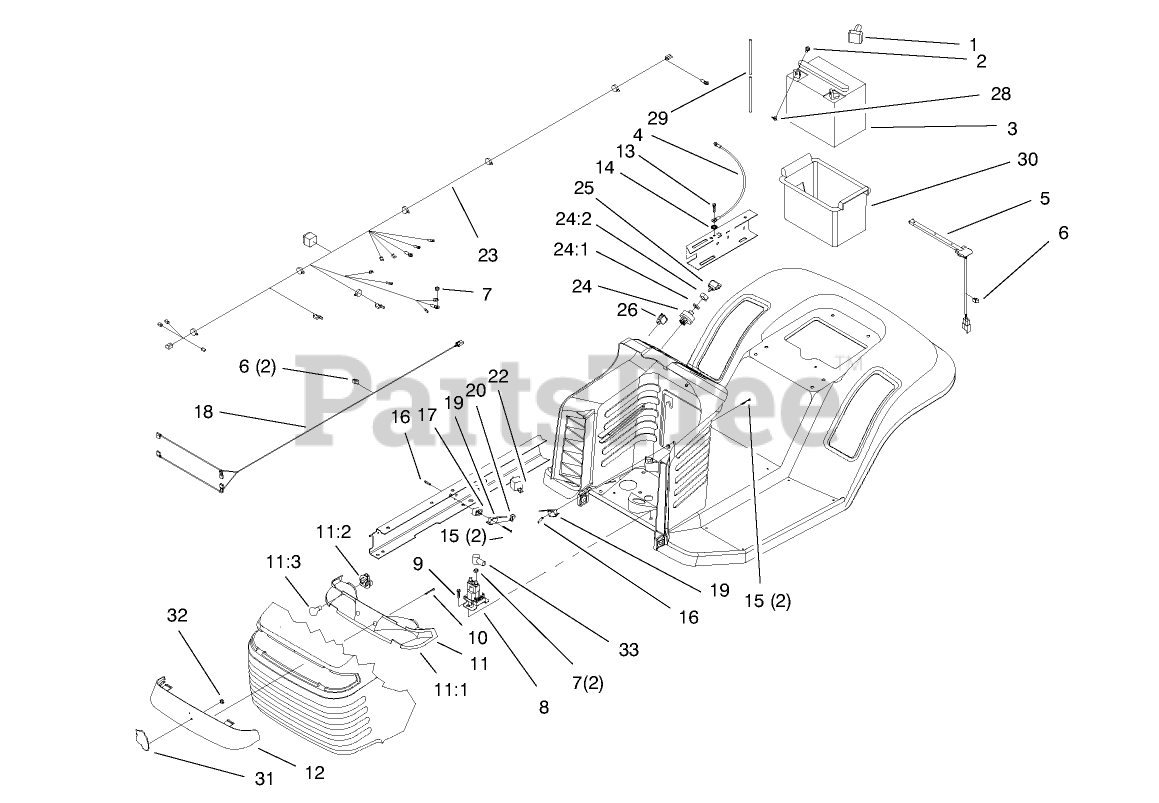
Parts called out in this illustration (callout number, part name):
1	BOOT-TERMINAL
2	SCREW-HH
4	WIRE ASM
5	SWITCH-SEAT
6	CLIP-RETAINER, WIRE
7	NUT-KEPS
9	SCREW-HWH
11	HEADLIGHT REFLECTOR ASM
11:1	REFLECTOR-LIGHT
11:3	BULB
12	LENS-HEADLIGHT
13	SCREW-HWH
14	WASHER-LOCK/EXT
15	SCREW-HH
16	NUT-SPEED
17	SPACER
18	HARNESS-WIRE, LIGHTS
19	SWITCH-MICRO
20	PLUNGER-SEAL
22	RELAY
23	WIRE HARNESS
24:1	WASHER-LOCK
24:2	NUT-HH
25	KEY-IGNITION
26	SWITCH-ROCKER
28	NUT-WING
29	TUBE-BATT DRAIN/80-2600
30	BOX-BATTERY
33	BOOT-TERMINAL INSULATOR
